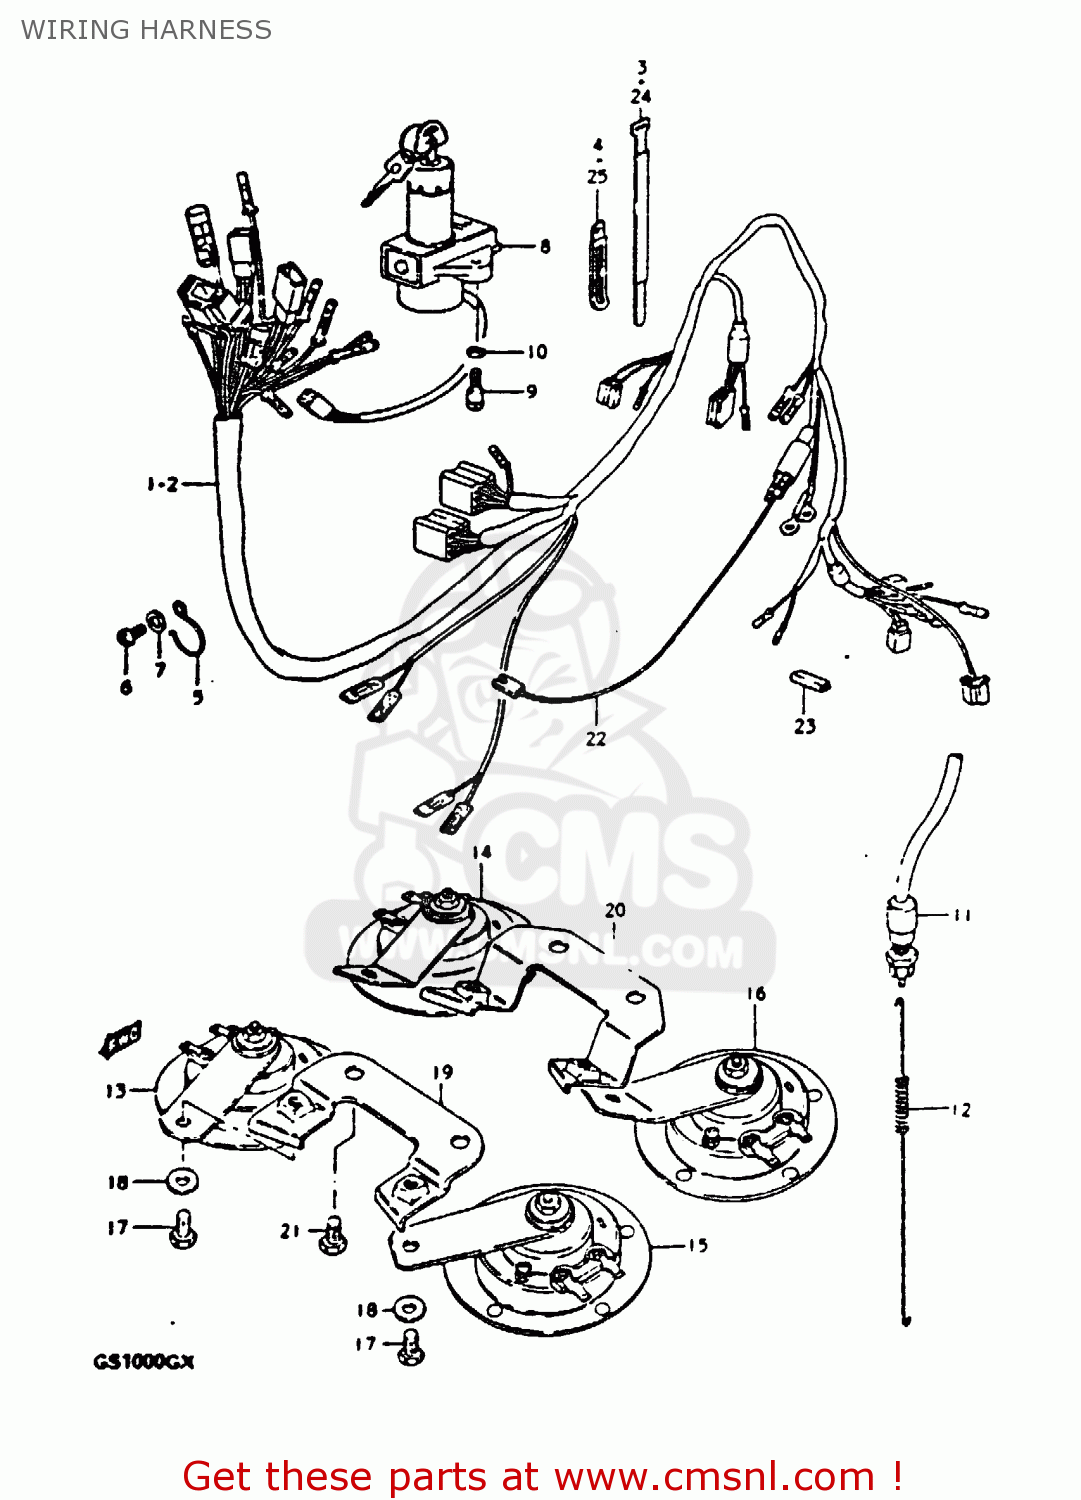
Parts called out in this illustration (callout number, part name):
1	HARNESS,WIRING
3	CLAMP
4	CLAMP
5	GUIDE,WIRING HARNESS
6	SCREW 6X12
7	WASHER
8	LOCK ASSEMBLY,STEERING
9	BOLT
10	LOCK WASHER
11	SWITCH ASSEMBLY,STOP LAMP
12	SPRING
13	HORN ASSEMBLY,LOW PITCH
14	HORN ASSEMBLY,LOW PITCH
15	HORN ASSEMBLY,HIGH PITCH
16	HORN ASSEMBLY,HIGH PITCH
17	BOLT
18	WASHER
19	BRACKET,HORN
20	BRACKET,HORN
21	BOLT 8X12
22	WIRE
23	PROTECTOR,WIRING HARNESS
24	CLAMP(L:120)
25	CLAMP
